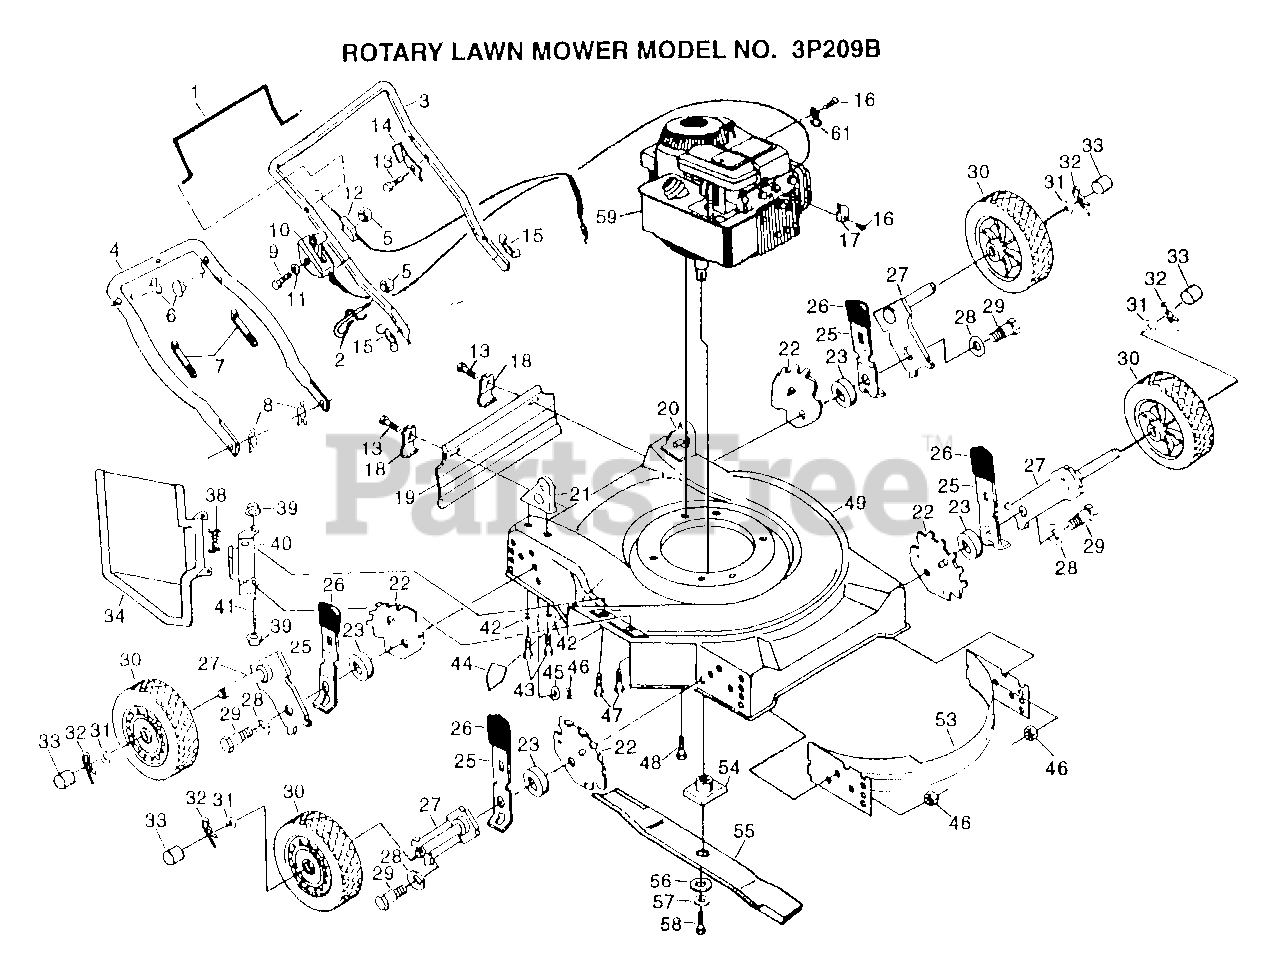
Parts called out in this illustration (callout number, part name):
1	CONTROL BAR PM
2	ROPE GUIDE
6	BOLT.HANDLE.LM
8	HAIRPIN COTTER
9	SCREW.HXHD.WASH.
10	CONTROL THROTTLE
12	"CABLE,ENG ZONE CO"
13	TAPPING SCREW
14	"BRKT,UPSTOP"
15	"NUT,WING PM"
16	SCREW PM
17	CABLE CLAMP
18	"BRKT,DEFL PM"
19	SKIRT.REAR.FGD.22
22	BRACKET.WHL.ADJ.9
25	SPRING SELECTOR
26	KNOB PM
27	AXLE ARM
28	"WASHER, BELLEVIL."
29	BOLT SHLD 3/8-16
30	WHEEL.ASM
31	WASHER
32	RETAINER CLIP PM
33	HUB CAP-PLASTIC
34	GUARD.DISCH.22SD.
35	BAIL.PLUG.MUL.22.
36	LATCH.PLUG.22SD
40	BRACKET.HINGE.W/F
41	ROD.HINGE.COMBI-C
42	STEEL WASHER
43	SCREW
44	DECAL HYT
46	LOCKNUT PM
48	SCREW
49	KIT.HSG.22SD.PUSH
53	BAFFLE.FRT/REAR
54	BLADE ADAPTOR
55	"BLADE.MULCH.22"""
56	"WASHER,HARDEN"
57	LOCKWASHER
58	SCREW
61	GUIDE CLIP PM
